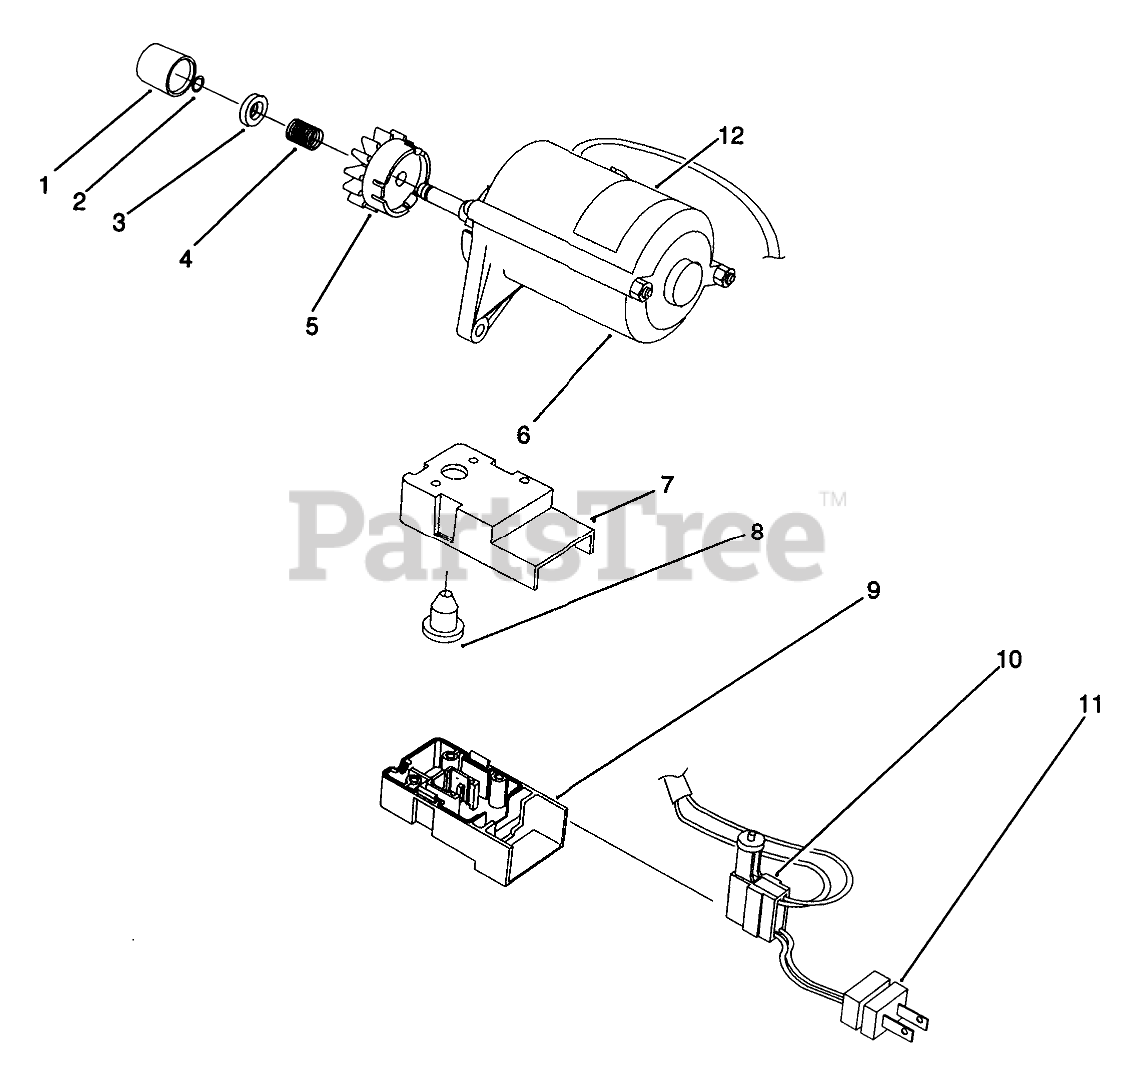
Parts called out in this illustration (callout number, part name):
1	CAP-PINION
2	RING-LOCK
3	PINION STOP
4	SPRING
5	Pinion Assembly
6	Starter Motor Assembly
7	Cap-Switch Housing
8	BOOT-SWITCH
9	OBS BASE X
10	SWITCH-STARTER
11	Plug
12	Decal-UL
